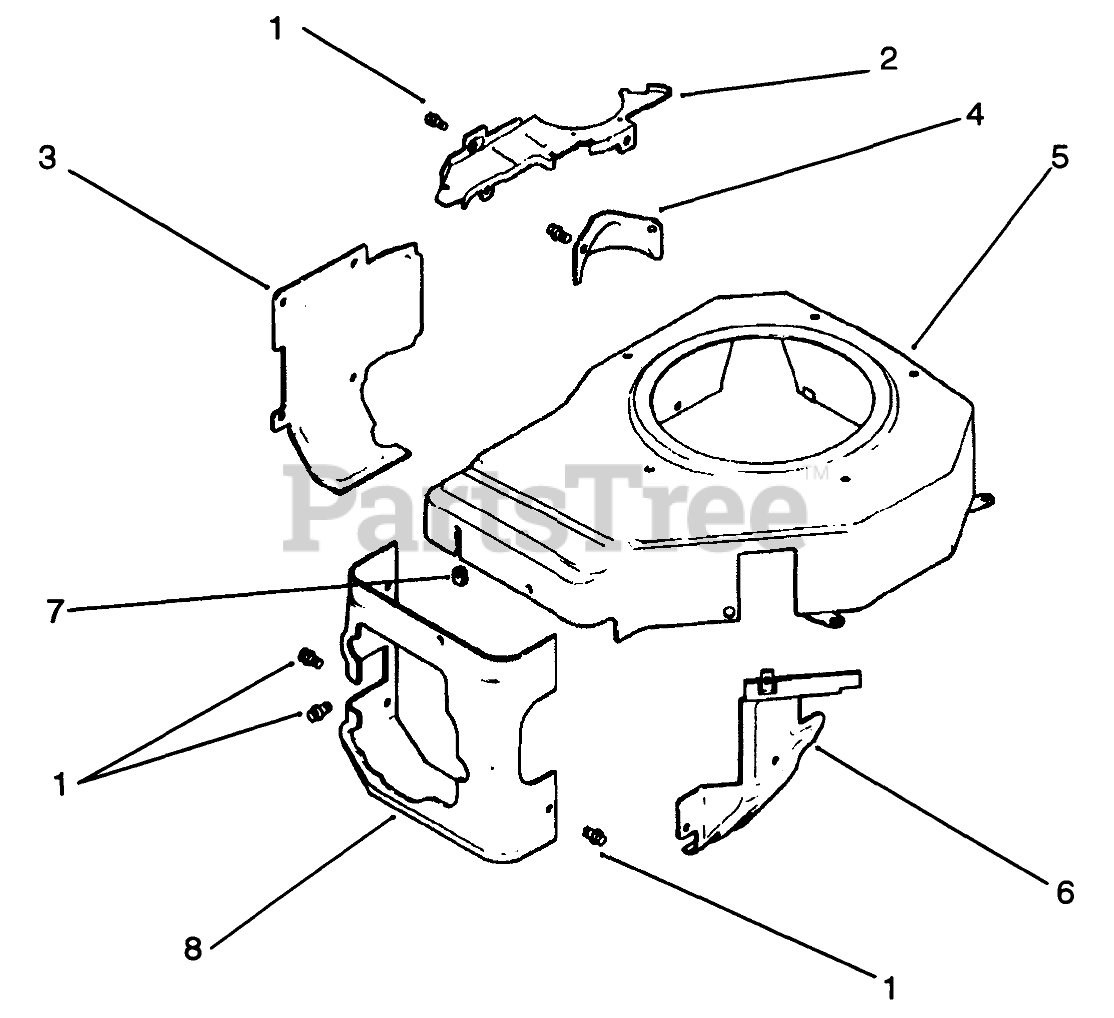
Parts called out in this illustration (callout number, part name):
2	Plate Blower
3	Babe-Cylinder Barrel
4	Cover-Starter
5	Cover-Housing
6	Bade-Carburetor
7	Grommet
8	Baffle-Cylinder Head
